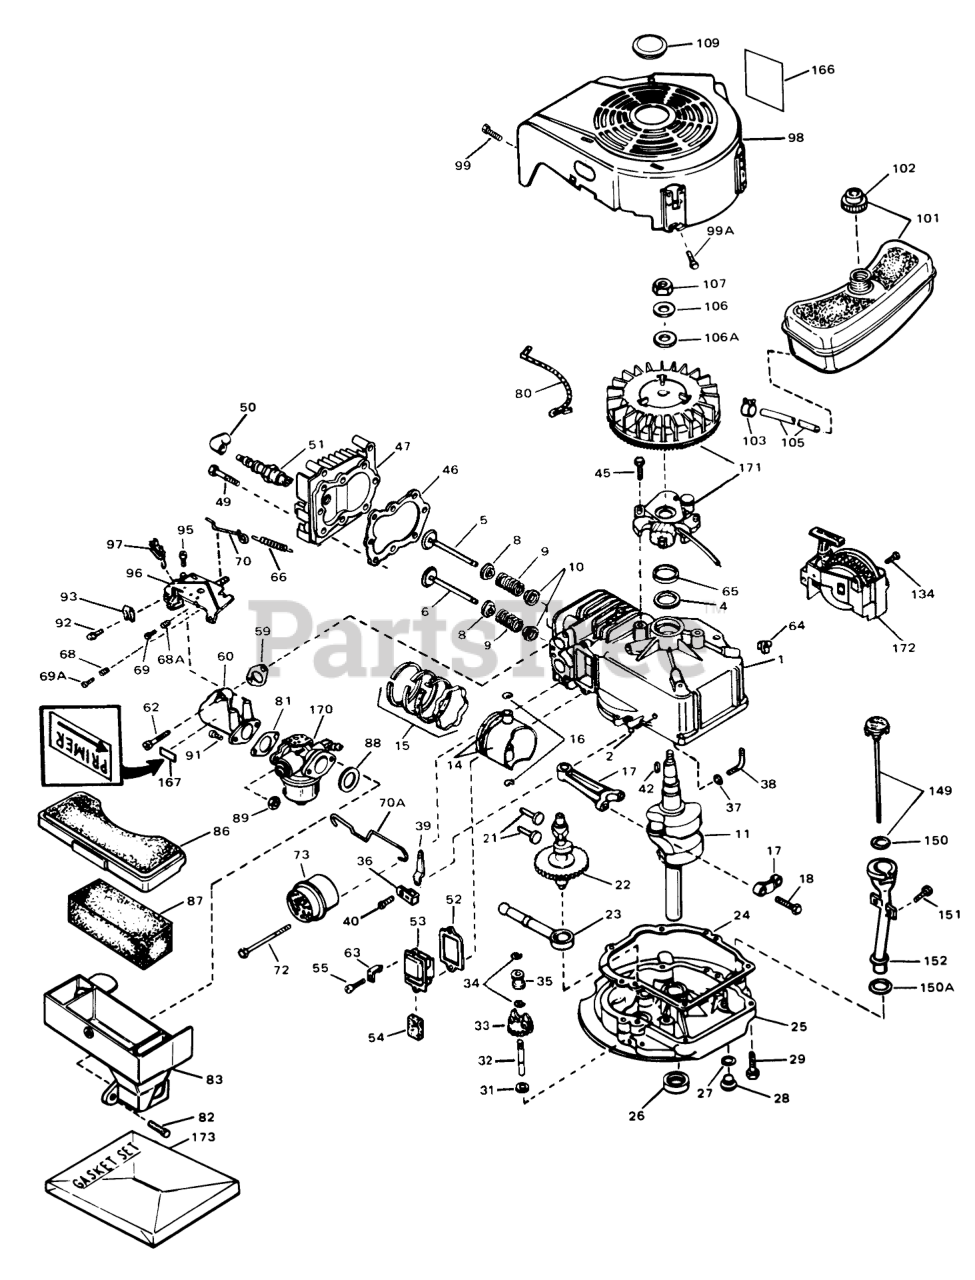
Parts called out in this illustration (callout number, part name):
1	Cylinder Assembly (Incl. Ref. #2 & 4)
2	Pin-Dowel
4	OIL SEAL
5	Valve, Intake (Std.) (Incl. Ref. #8, 9 & 10)
5	Valve, lntake (1 /32" Oversize) (Incl. Ref. #8, 9 & 10)
6	Valve, Exhaust (Std.) (Incl. Ref. #8, 9 & 10)
6	Valve, Exhaust (1/32" Oversize) (Incl. Ref. #8, 9, & 10)
8	Cap-Upper Valve Spring
9	Spring-Valve
10	Cap-Valve, Spring
11	Crankshaft
14	Piston, Pin & Ring Assy. (Std.) (Incl. Ref. #15 & 16)
14	Piston, Pin & Ring Assy. (.010 Oversize) (Incl. Ref. #15& 16)
14	Piston, Pin & Ring Assy. (.020 Oversize) (Incl. Ref. #15&16)
15	Piston Ring Set Std.
15	Piston Ring Set .010 O.S.
15	Piston Ring Set .020 O.S.
16	Ring-Retaining, Piston Pin
17	Rod Assembly Connecting (Incl. Ref. #18)
18	Bolt-Rod, Connecting
21	Lifter-Valve
22	Camshaft(Mech.Comp. Release)
23	Oil Pump ASM
24	26750A Gasket, Mounting Flange
25	Flange Assy., Mounting (Incl. Ref. #26, 27, 28 & 32)
26	Seal Oil
27	28833 Gasket, Oil Drain Plug
28	Plug Oil Drain
29	Screw (1/4-20 x 1-1/4)
31	Washer-Flat
32	Shaft-Governor
33	Gear Assy., Gov. (Incl. Ref. #31)
34	Ring-Retaining
35	Spool-Governor
36	Clamp-Lever, Governor
37	Washer-Flat
38	Rod, Governor (Incl. Ref. #37)
39	Lever, Governor
40	Screw, Hex Washer Hd.
42	Key-Flywheel
46	29953B Gasket, Cylinder Head
47	2025A67 ADD.ASSEMBL
49	Screw (5/16-18x1-1/2)
50	Cover-Spark Plug
51	Plug, Spark (J17LM or equiv.)
51	Plug, Spark (Champion RCJ-8)
52	31619 Gasket, Breather
53	Breather Assembly (Incl. Ref. #52 & 54)
54	Element-Breather
59	32649 Gasket, Intake Pipe
60	Pipe, Intake
62	Screw (1/4-20 x 1)
63	Retainer Clip
64	51004 GIL ROTARY TI
65	Gasket Stator
66	Spring Governor
68	61709/GIL1515A/95-5
68A	Spring-Compression
69	Screw
69A	Screw
70	2035A67 ADD.ASSEMBL
70A	Link-Throttle
73	Muffler Kit (Incl. Ref. #72)
80	Wire-Ground
81	26756 Gasket, Carburetor
83	Body, Air Cleaner
86	Cover Air Cleaner
87	Filter-Air Cleaner
88	34338 Gasket, Air Cleaner
89	Nut and Lock Washer (1/4-28)
91	Screw (1/4-28 x 7/8)
92	Screw (10-32 x 3/8)
93	Conduit
95	Screw (10-24 x 9/16)
96	Control Assy., Speed (Incl. Ref. #68, 68A, 69, 69A & 97)
97	Terminal
98	Housing, Blower
99	Screw (10-24 x 9/16)
99A	Screw
101	Tank Assy., Fuel (Incl. Ref. #102)
102	Cap, Fuel
103	Clamp-Line, Fuel
105	Line-Fuel (8.62)
106	Washer-Spring
106A	Washer Flat
107	Hex Nut
109	Plug, Screen
134	Screw (1/2-20x5/8)
149	Dipstick, Oil (Incl. Ref. #150) (Twist Lock)
151	Screw (10-32 x 1/2)
152	Tube-Oil Fill
166	Decal-Instruction
167	Decal, Instruction
170	Carbu retor (Incl. Ref. #81)
172	Starter-Sidemount
173	Gasket Set
